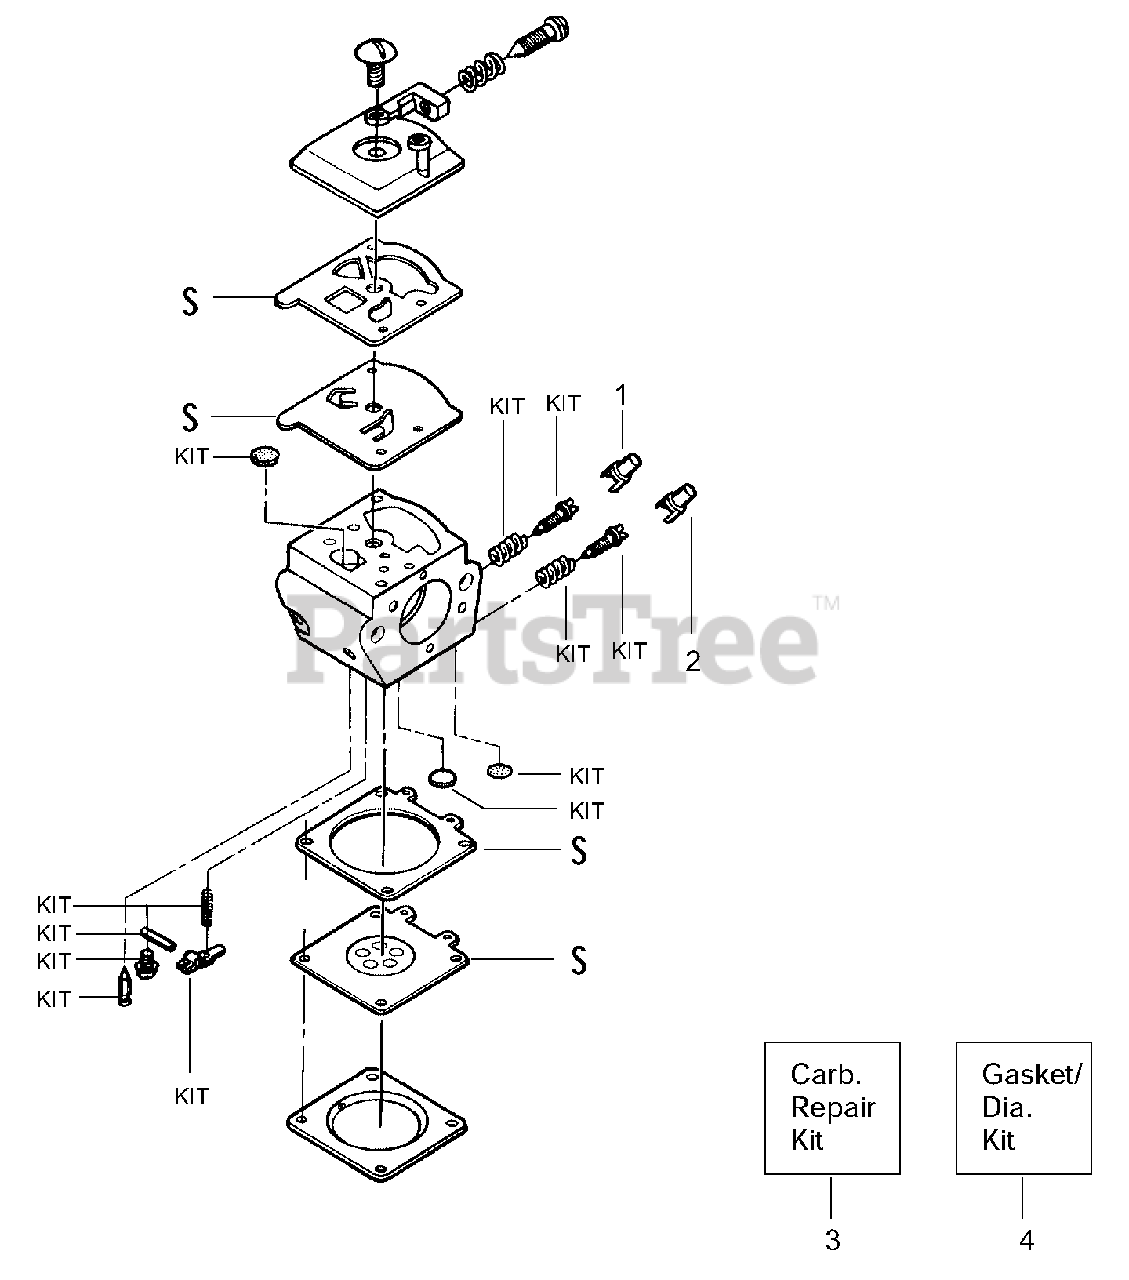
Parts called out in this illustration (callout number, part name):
1	Limiter Cap- High
2	Limiter Cap- Low
3	Carburetor Repair Kit
4	Gasket Diaphragm Kit
